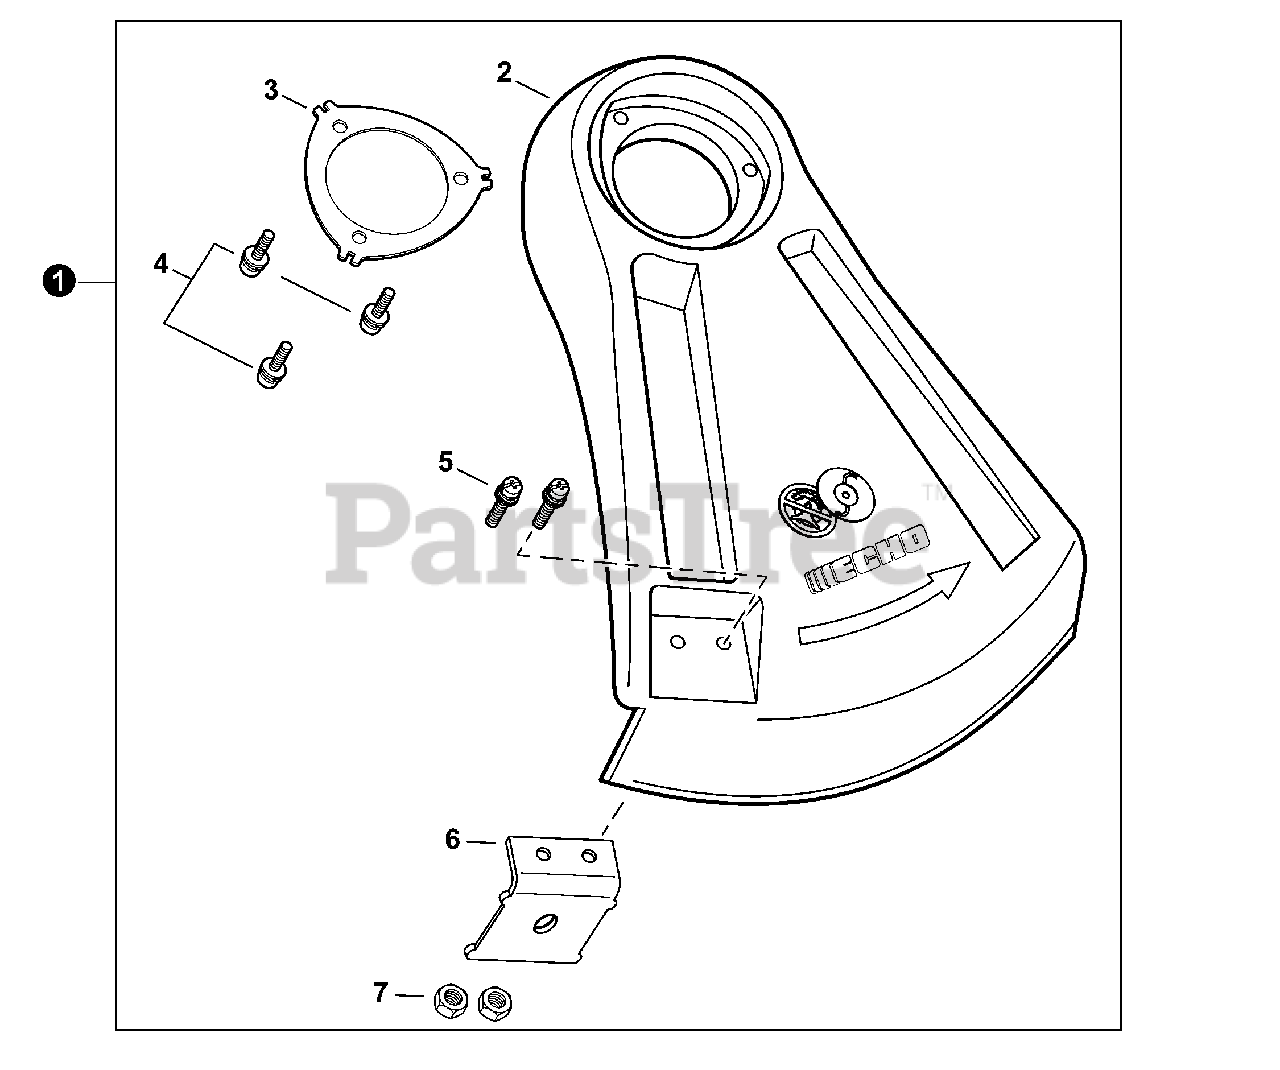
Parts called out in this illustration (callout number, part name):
1	DEBRIS SHIELD KIT
2	SHIELD, DEBRIS PLASTIC
3	PLATE, SHIELD
4	SCREW 5×20
5	SCREW 5×16
6	CUTTER, LINE
